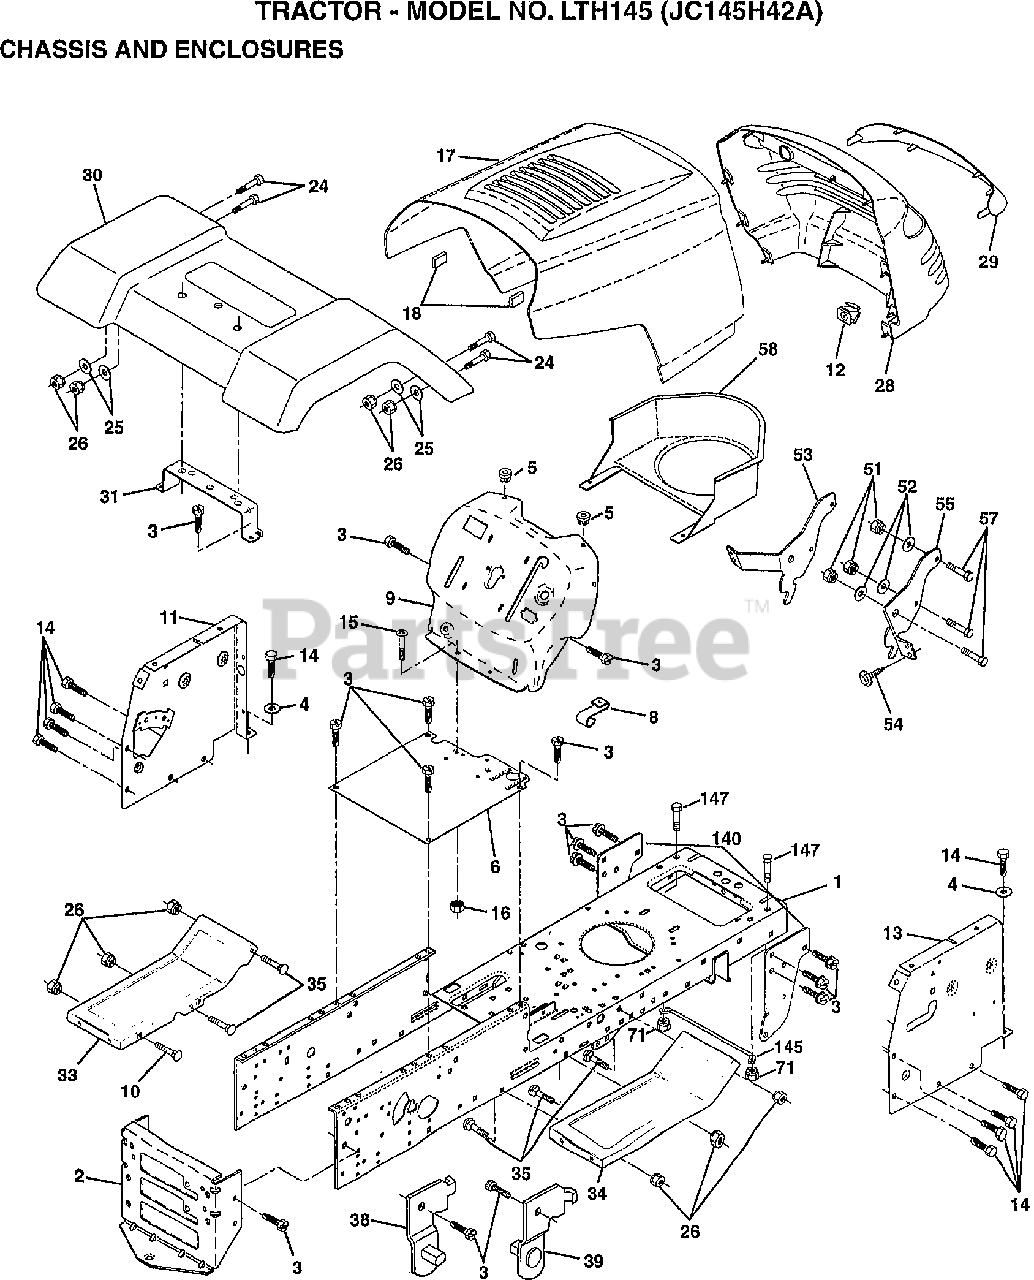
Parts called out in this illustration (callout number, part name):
3	SCREW THDROL 3/8-16X3/4 TY-TT
4	WASHER 13/32X3/4X16 GA
10	BOLT CARRIAGE 3/8-16X1
14	SCREW THDROL 3/8-16X1/2 TY-TT
15	SCREW MACHINE TRHD 5/16-18 X 3/4
16	NUT, KEPS 5/16-18
18	"BUMPER,HOOD T"
24	BOLT FIN HEX 3/8-16 X 1
25	WASHER
26	LOCKNUT
35	BOLT RDHD SHT SQNK 3/8-16 X 3/4
51	NUT LOCK HEX W/INS 1/4-20
52	WASHER 9/32 X 7/8 X 16 GA
54	SCREW LOCK SPIDER #8 X 7/8
57	BOLT HEX 1/4-20 X 3/4
71	NUT CROWNLOCK 1/4-20
147	BOLT HEX HD 1/4-20 X 3/4
